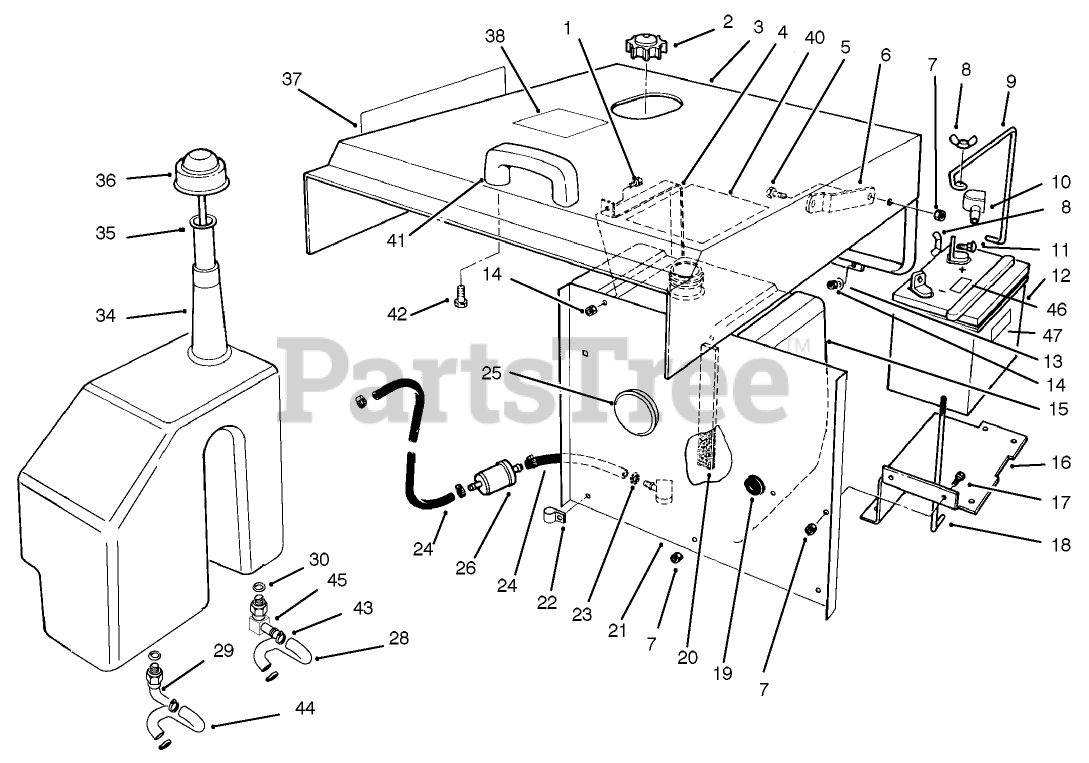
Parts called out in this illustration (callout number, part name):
1	SCREW-HH
2	GAS CAP ASM
3	Hood
4	Strap-Fuel Tank
5	SCREW-HH
6	UPPER HOOD STOP
7	NUT-LOCK, NI
8	NUT-WING
9	BATTERY CLAMP
10	BOOT-TERMINAL, RED
11	BOLT-CARR
12	BATTERY
13	WASHER-FLAT
14	NUT-LOCK, NI
15	TANK-FUEL
16	Support-Battery
17	SCREW-HH
18	ROD-SUPPORT, BATTERY
19	GROMMET
20	TANK SPONGE
21	Shield-Heat
23	CLAMP-WORM
24	GAS HOSE
25	PLUG BUTTON CAP
26	FILTER - FUEL
29	Adapter-Hydraulic (Incl. Ref. #30)
30	O-RING
34	RESERVOIR - OIL
35	SCREEN-FILLER
36	CAP WA
37	DECAL - GM 120
38	DECAL-REFUELING
40	DECAL - SERVICE PL120
41	HANDLE-DOOR
42	SCREW-HWH
43	CLAMP-HOSE
44	HOSE-RESV TO PUMP
45	Adapter-Hydraulic (Incl. Ref. #30)
46	DECAL-BATTERY
47	DECAL-DANGER
